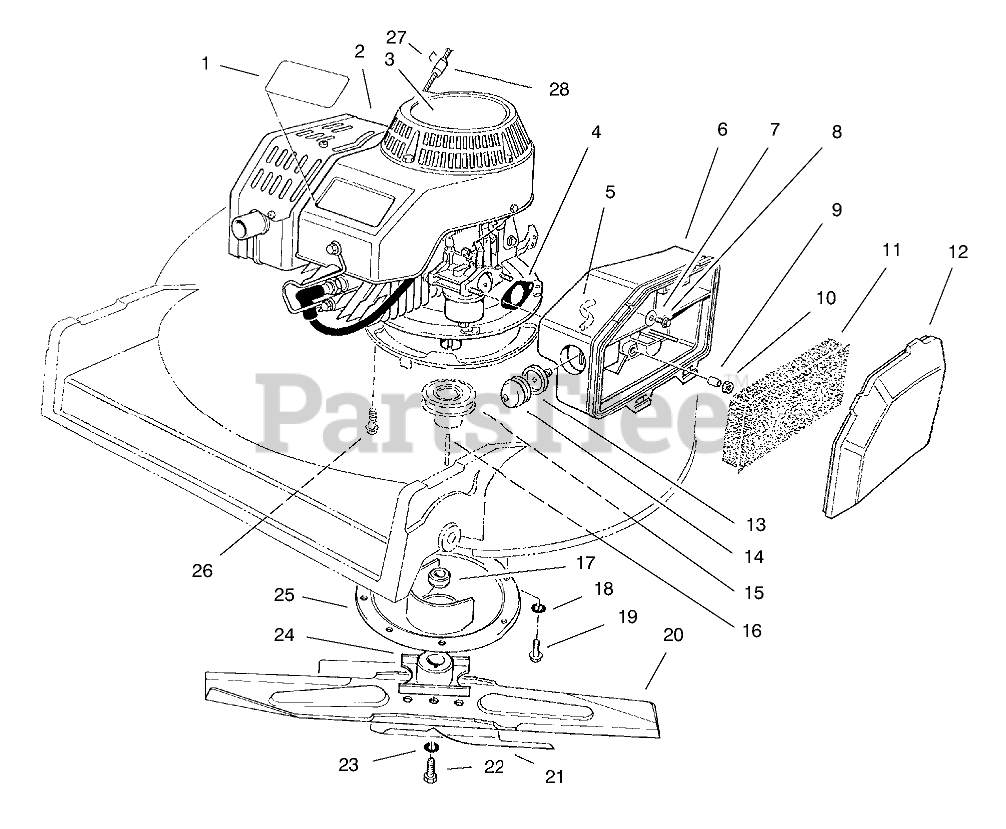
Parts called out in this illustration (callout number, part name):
1	DECAL - PROLINE
2	ENGINE ASM
3	DECAL-2 CYC RECOIL COMM
4	GASKET-AIR CLEANER
5	HOSE-PRIMER
6	BODY-AIR CLEANER
7	WASHER-FLAT
8	SCREW-HH
9	SPACER
11	ELEMENT-AIR CLEANER
12	COVER-AIR CLEANER
13	BODY-PRIMER
14	BULB-PRIMER
15	PULLEY-DRIVER
16	KEY-SQUARE
17	SPACER-BLADE RETAINER
18	WASHER-LOCK, INTERNAL
19	SCREW-HWHTF
20	Blade
21	Accelerator
22	SCREW-BLADE
23	WASHER-LOCK
24	RETAINER-BLADE
25	PROTECTOR-CRANKSHAFT
26	SCREW-HHF
27	Staple
28	STOP-ROPE
